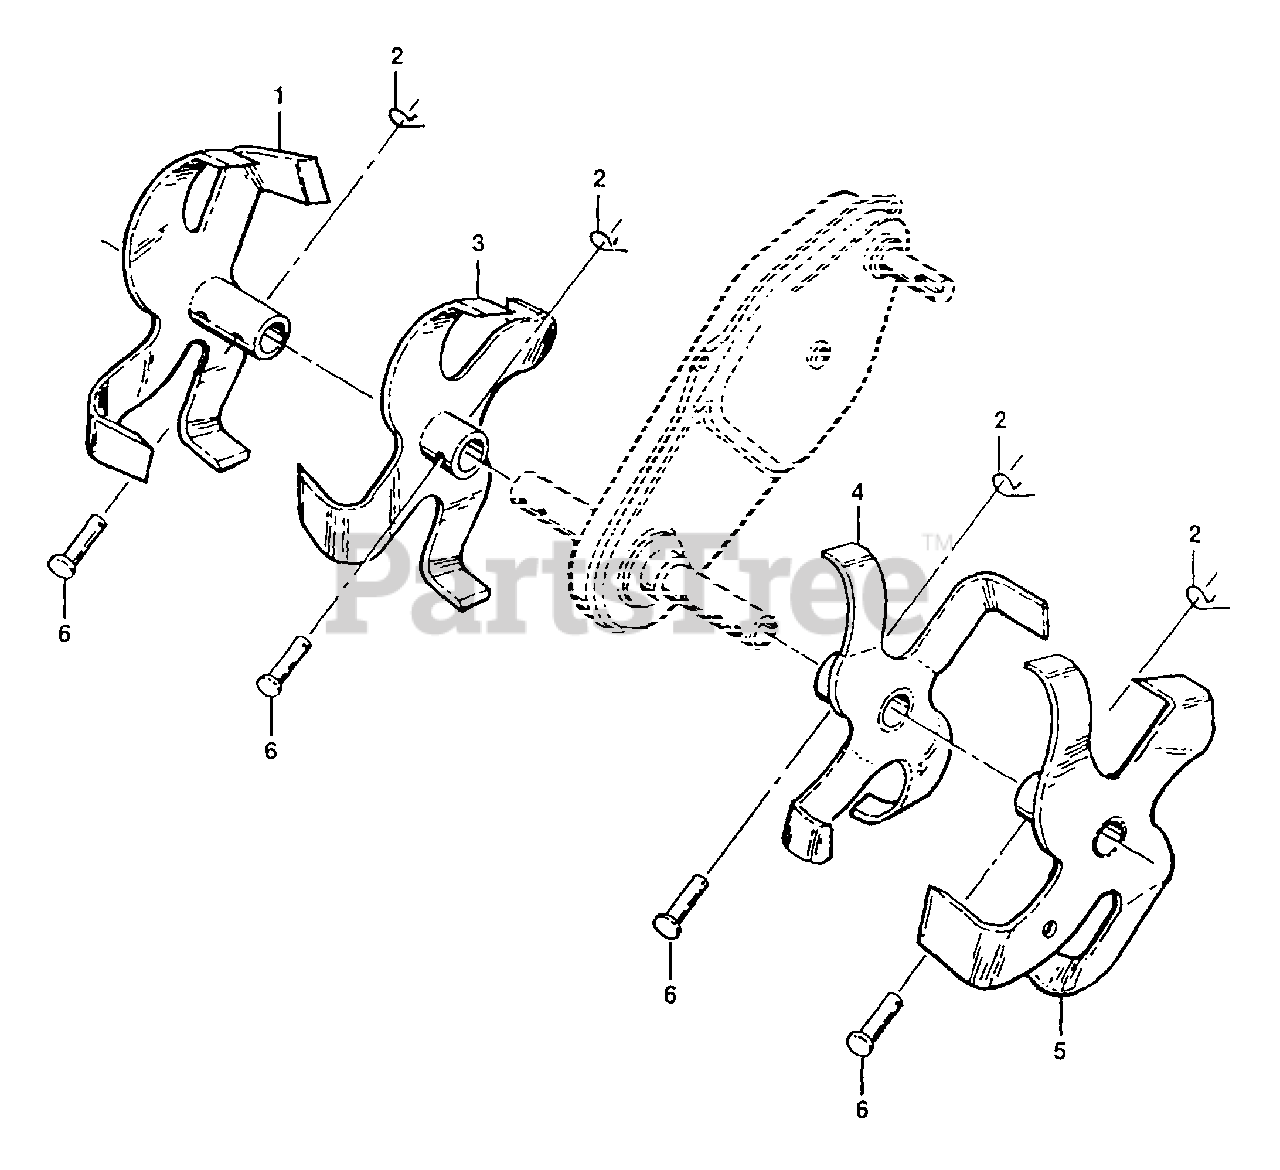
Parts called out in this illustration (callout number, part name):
1	Tine, Outer, R.H. (AYP part number)
2	Clip, Hairpin
3	Tine, Inner, R.H. (AYP part number)
4	Tine, Inner, L.H. (AYP part number)
5	Tine, Outer, L.H. (AYP part number)
6	Pin, Clevis
